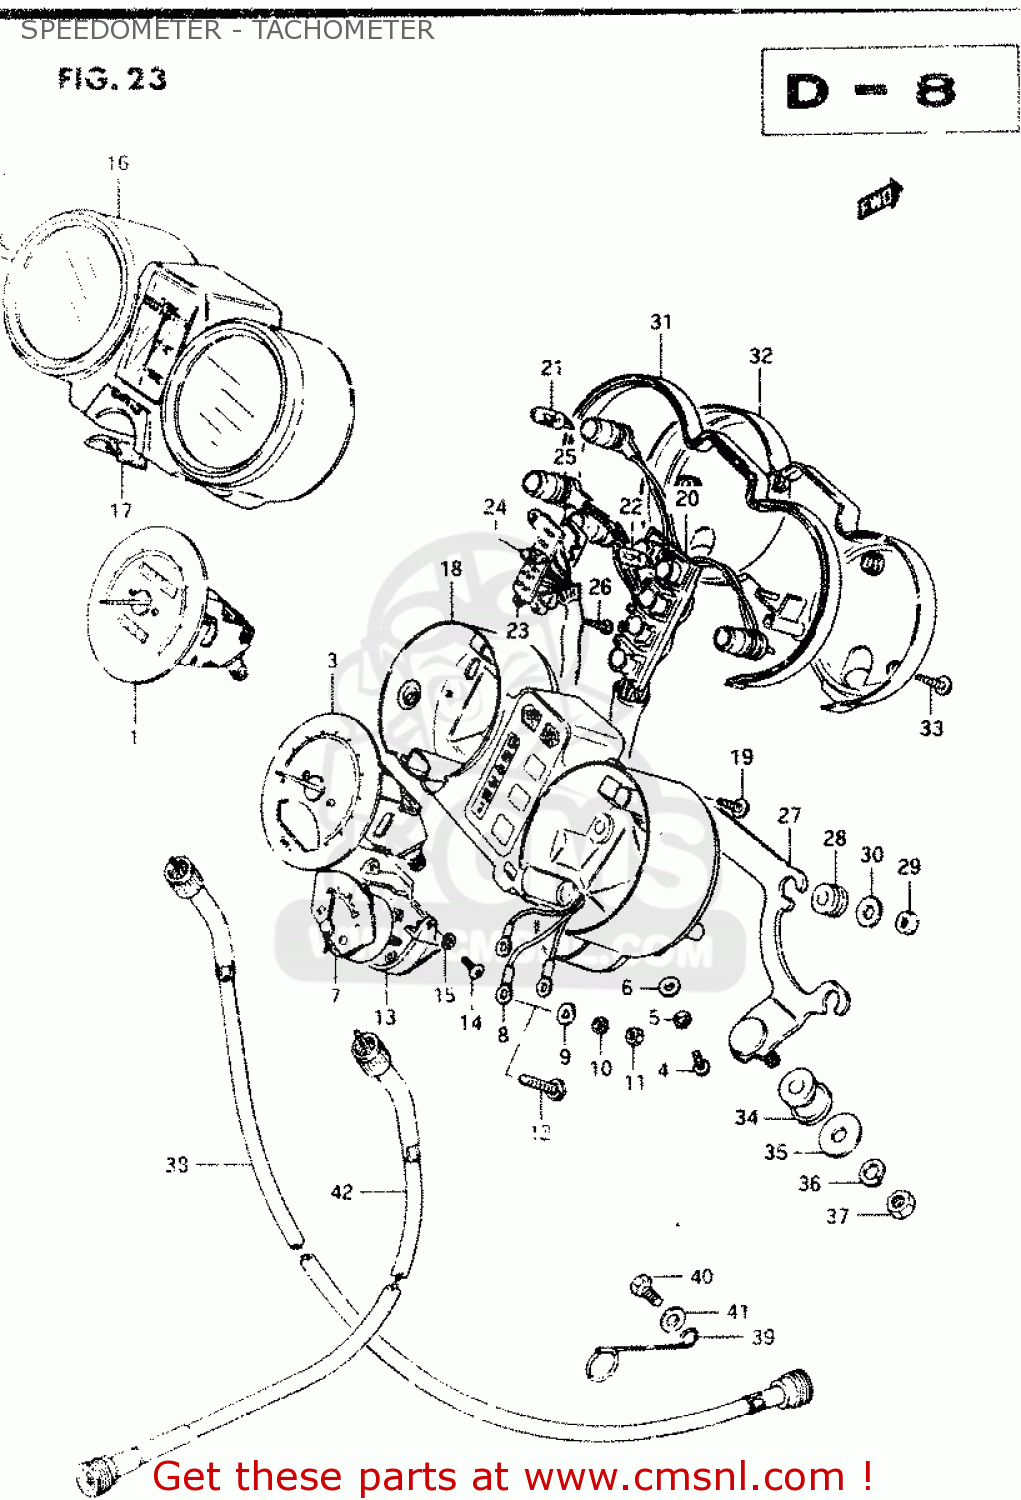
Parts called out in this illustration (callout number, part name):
1	SPEEDOMETER (KILO)
2	KNOB
3	TACHOMETER
4	SCREW 4X10
5	WASHER
6	LOCK WASHER
7	METER,FUEL
8	WIRE,FUEL METER LEAD
9	WASHER,FUEL METER
10	LOCK WASHER
11	NUT 3MM
12	SCREW(3X22)
13	BRACKET,FUEL METER
14	SCREW
15	LOCK WASHER
16	HOOD,METER
17	SEAL,IGNITION SWITCH
18	CASE, INNER
19	SCREW
20	SOCKET
21	BULB(12V3.4W,T10)
22	BULB(12V1.7W,T10,WB121)
23	SOCKET,GEAR INDICATOR
24	BULB(14V1.12W,BQ041-32503B)
25	COVER,INDICATOR,LOWER
26	SCREW
27	BRACKET,COMBINATION METER
28	CUSHION,METER
29	NUT
30	WASHER (5.5X16X1.2)
31	COVER,METER,UNDER
32	COVER,LWR
33	SCREW
34	CUSHION,METER BRACKET
35	WASHER (8.5X20X1.6)
36	WASHER,LOCK,8.
37	NUT
38	CABLE ASSY,SPEEDOMETER
39	CLAMP,SPEEDOMETER CABLE
40	BOLT, UPPER
41	WASHER
42	CABLE ASSEMBLY,TACHOMETER
